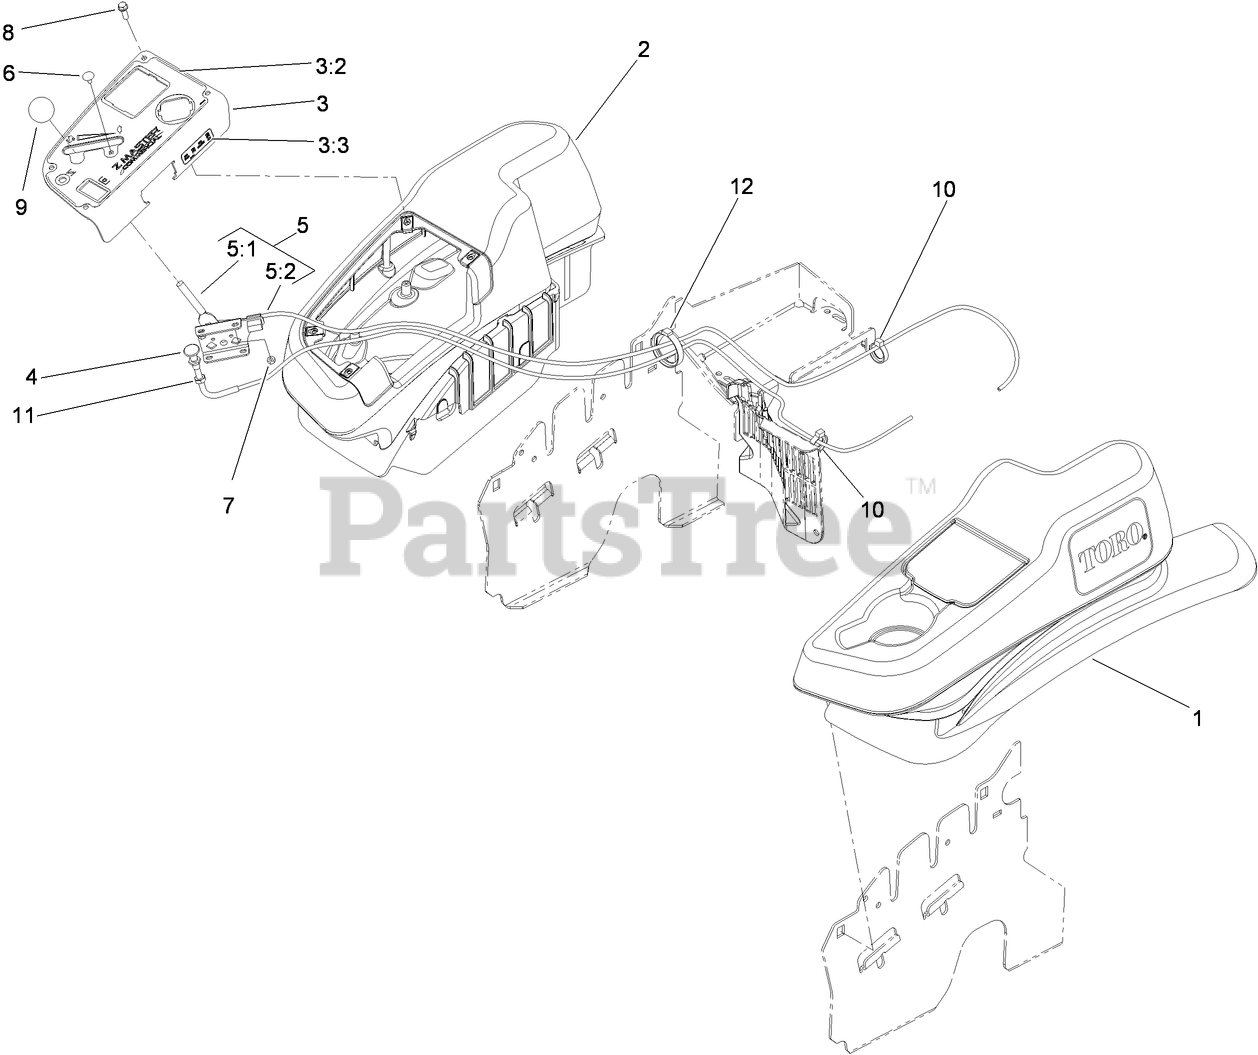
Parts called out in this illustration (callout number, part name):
1	LH NARROW FENDER/CONSOLE ASM
2	RH NARROW FENDER/CONSOLE ASM
3	CONTROL PANEL ASM
3:2	DECAL-PANEL, CONTROL
3:3	DECAL-FUSES
4	CONTROL-CHOKE
5	THROTTLE CONTROL ASM
5:1	LEVER-THROTTLE
5:2	CABLE-THROTTLE
6	BOLT-CARR
7	NUT-LOCK, NI
8	SCREW-HWH
9	KNOB-BALL
10	CLAMP-HOSE
11	NUT-HJ
12	CLAMP-HARNESS
